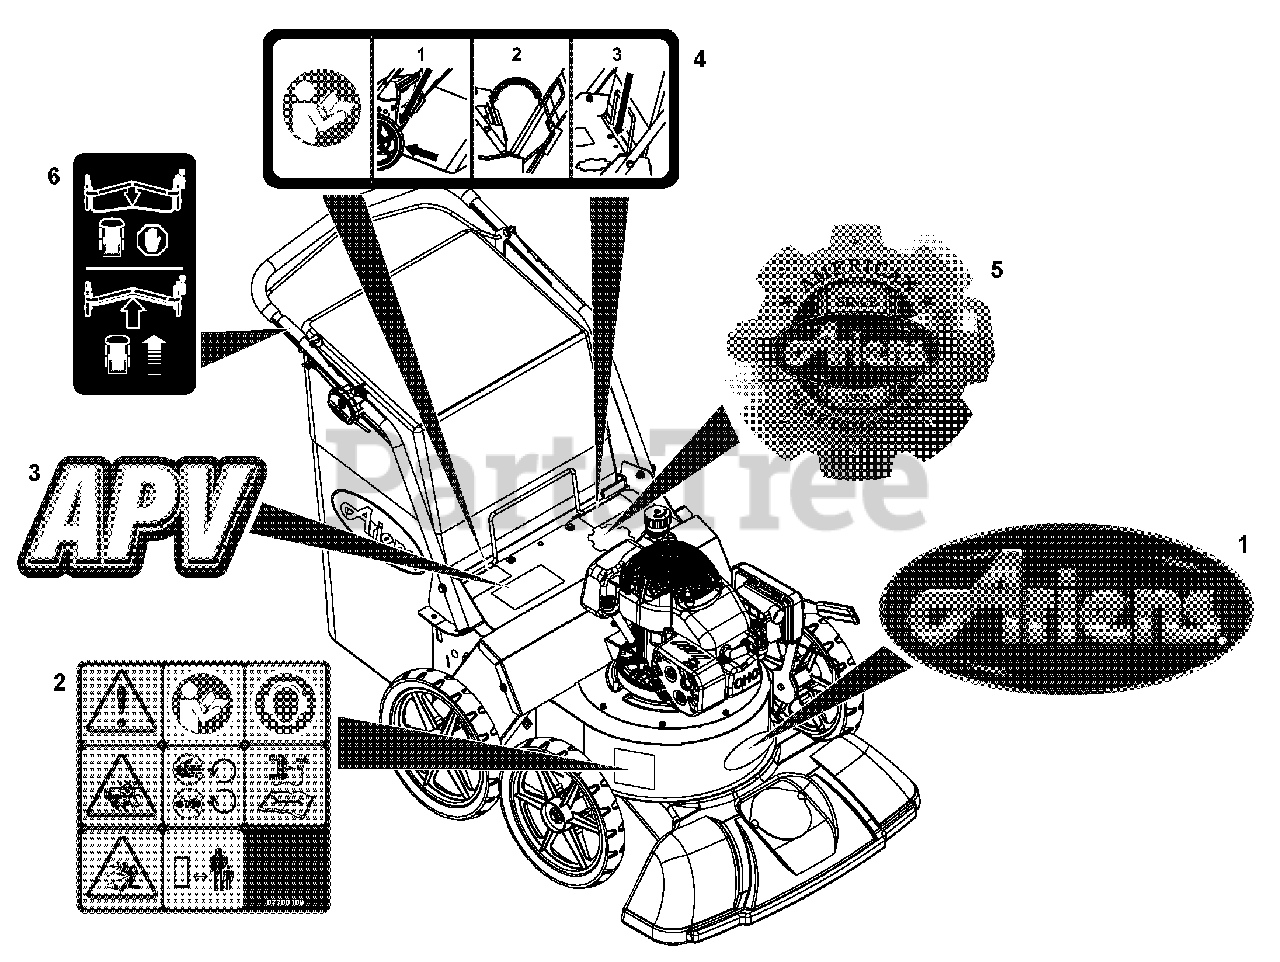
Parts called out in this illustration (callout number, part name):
1	DECAL, ARIENS JEWEL (LARGE)
2	DECAL,VAC WARNING ISO
3	DECAL - APV
4	DECAL, APV BAG INSTALLATION
5	DECAL, ARIENS HERITAGE - LARGE
6	DECAL, DRIVE CONTROL
